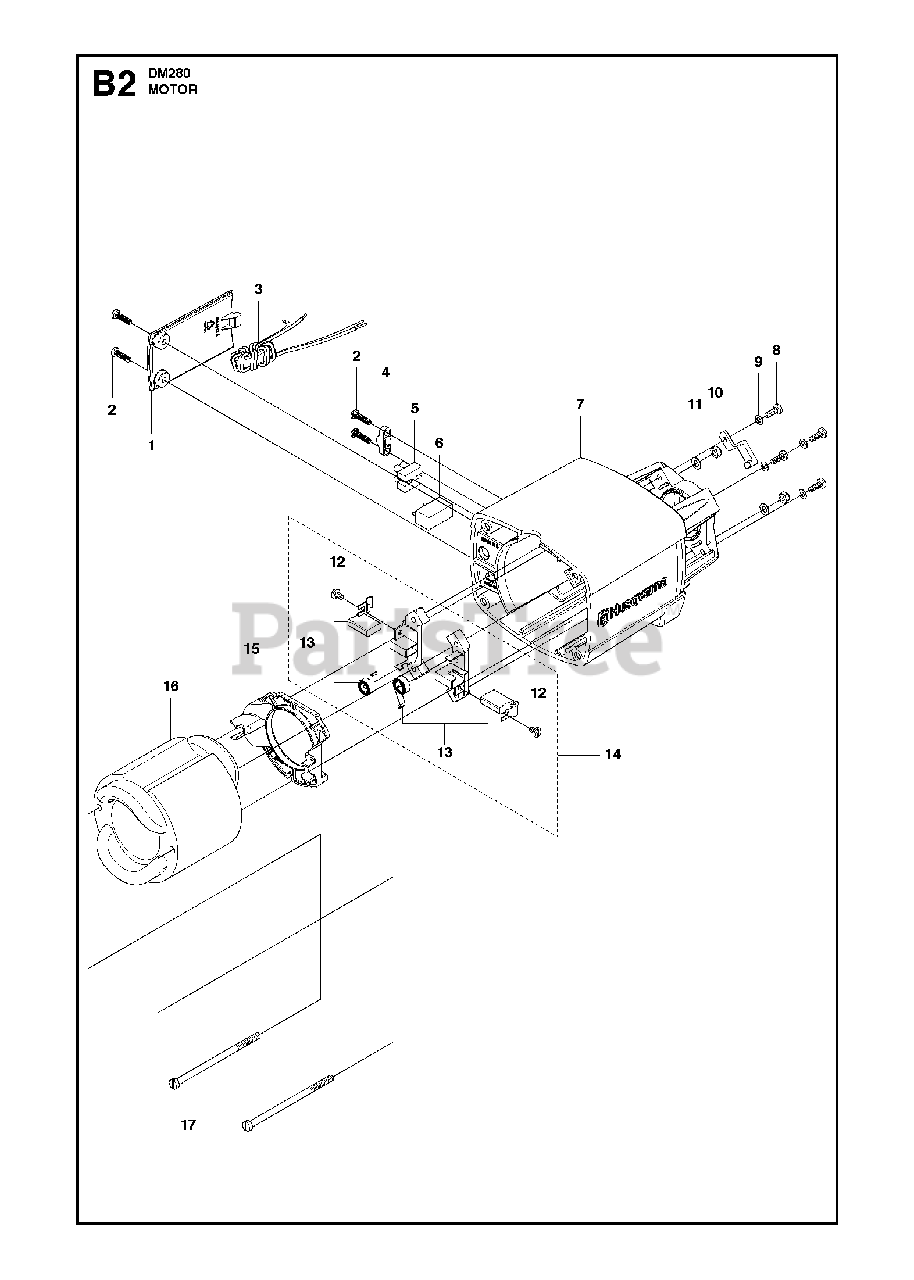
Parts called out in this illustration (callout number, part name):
9	SPRING WASHER
11	SPRING WASHER
13	BRUSH KIT2 pcs in pack
14	BRUSH HOLDER
16	STATOR ASSY120V
16	STATOR ASSY230V
